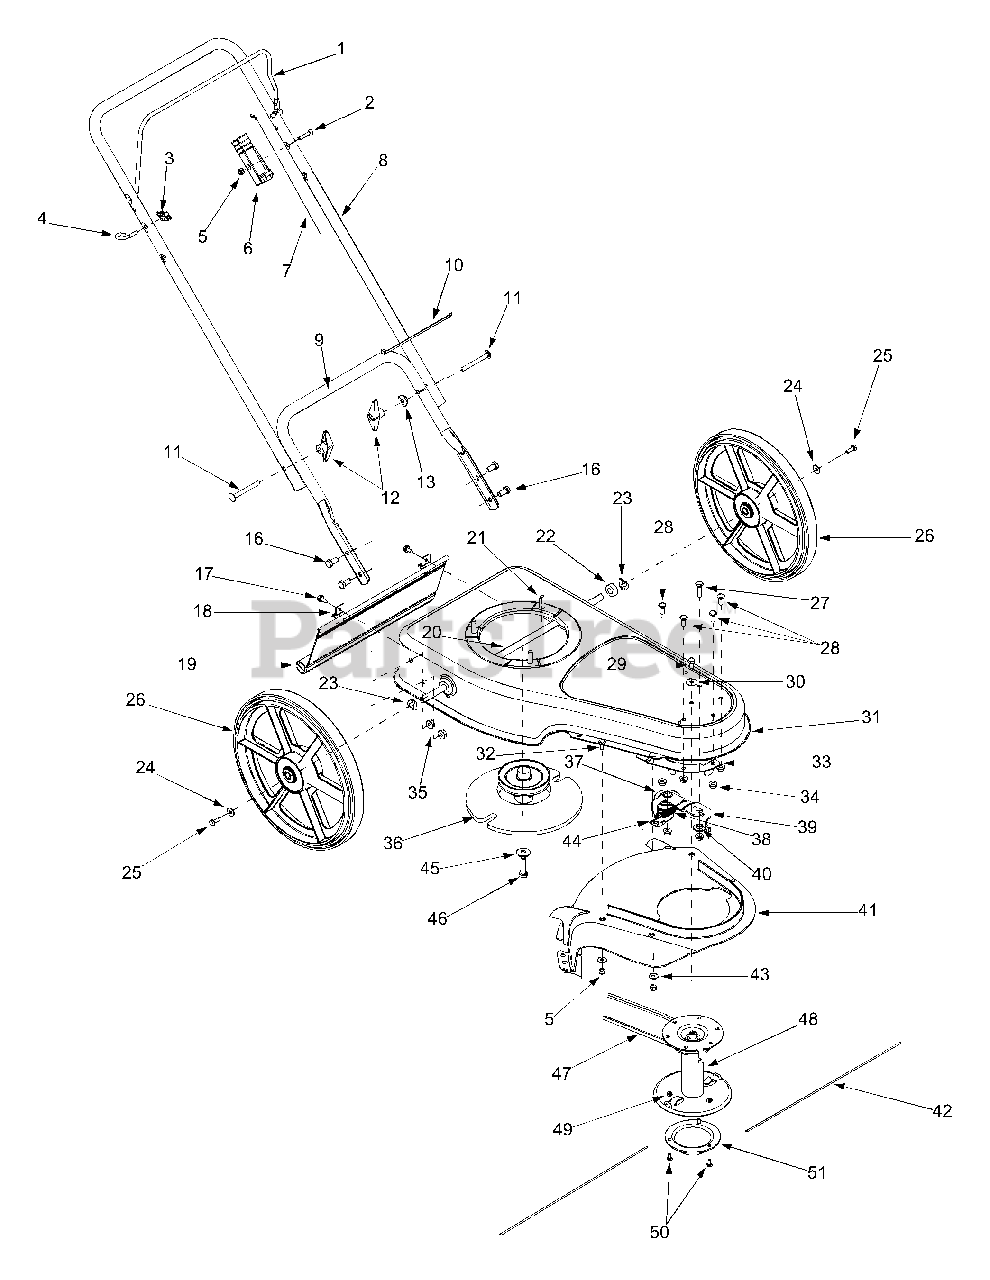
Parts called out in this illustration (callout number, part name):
3	Knob 1/4-20
4	Eye Bolt 1/4-20
5	Hex Lock Nut
6	Throttle Housing
7	Throttle Cable
11	Carriage Screw 5/16-18 x 2.0
12	Wing Nut 5/16-18
13	Saddle Washer.320 ID x.93 OD
16	Hex Cap Screw 3/8-16 x.750
17	Hex Washer Screw 1/4-14 x.625
18	Trail Shield Clip
19	Trail Shield
20	Axle Assembly
21	Hex Washer Screw 3/8-16 x.250
22	Spacer.51 ID x 1.00 OD x.38
23	Spacer Washer.50 ID x 1.0 OD
24	Bell Washer.265 ID x.75 OD
25	Hex Cap Screw 1/4-20 x.75
26	Wheel 14 x 1.8 Bar Gray
27	Screw 5/16-18 x 1.25
28	Screw 5/16-18 x.75
29	Hex Cap Screw 5/16-24 x.625
30	Bell Washer.325 ID x.930 OD
34	Flange Lock Nut 5/16-18
35	Flange L-Nut 3/8-16
36	Flywheel Pulley
37	Idler Pulley
38	Extension Spring.50 ID x 3.375
39	Idler Bracket Assembly
40	Idler Spacer
41	Trimmer Deflector Assembly
42	Trimmer Line.130 Dia
43	Flat Washer.28 ID x.74 OD
45	Bell Washer.396 ID x 1.140 OD
46	Hex Cap Screw 3/8-24 x 1.50
47	V-Belt
48	Spindle Assembly
49	Hex Lock Nut 1/4-20
50	Hex Cap Screw 1/4-20 x.50
51	Skid
